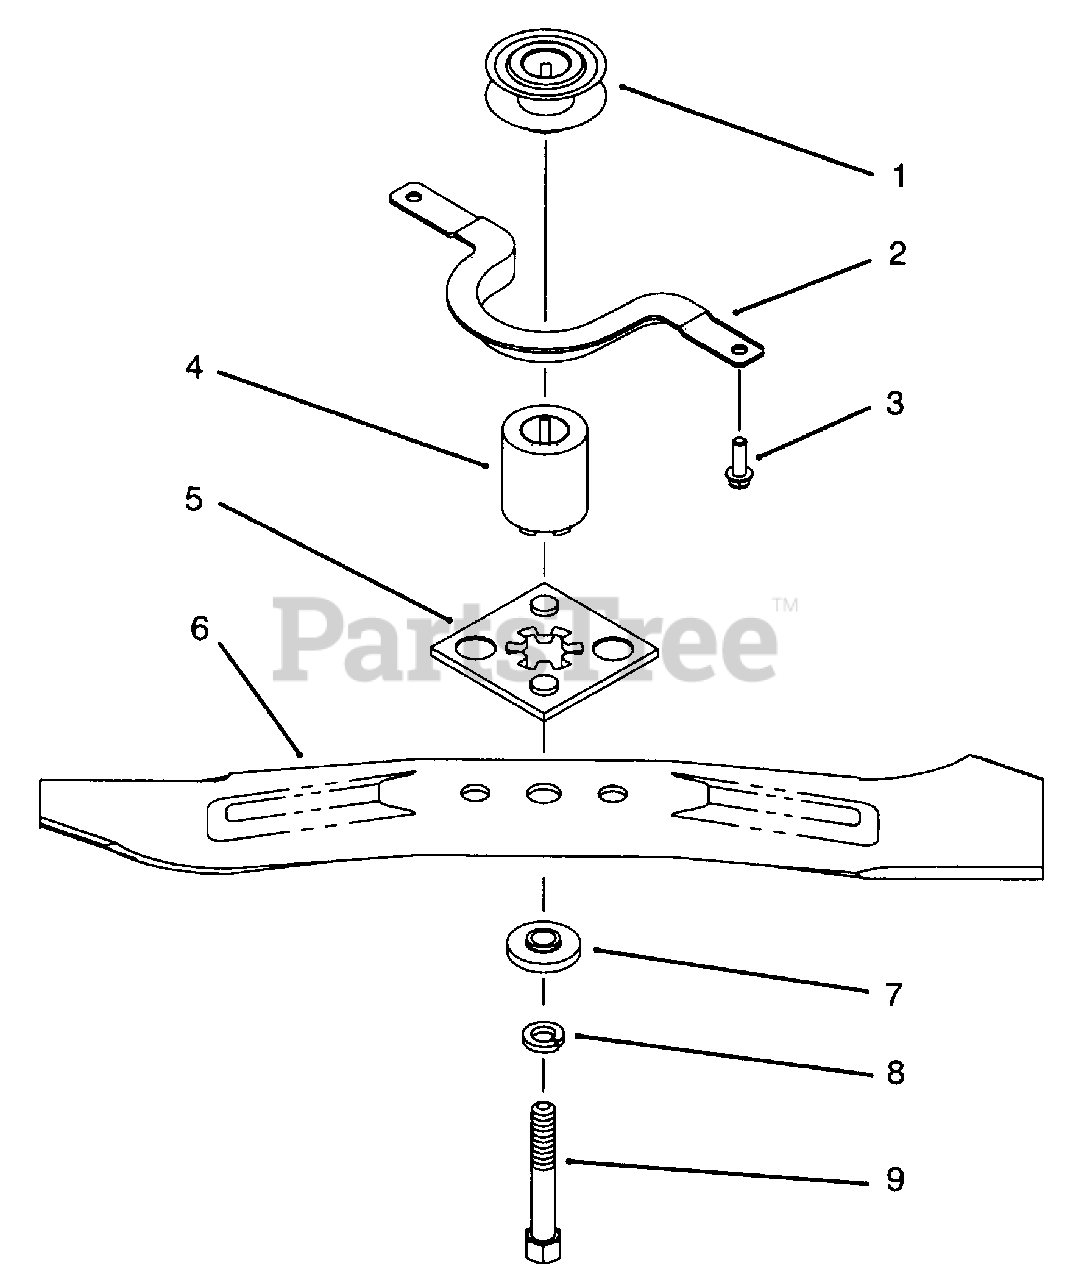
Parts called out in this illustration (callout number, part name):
1	Pulley-Driver
2	Guide-Belt
3	Screw-Tapping
4	Hub-Blade Driver
5	Plate-Blade Driver
6	Blade-48cm
7	Spacer-Blade
8	Washer-Lock
9	Bolt-Blade
